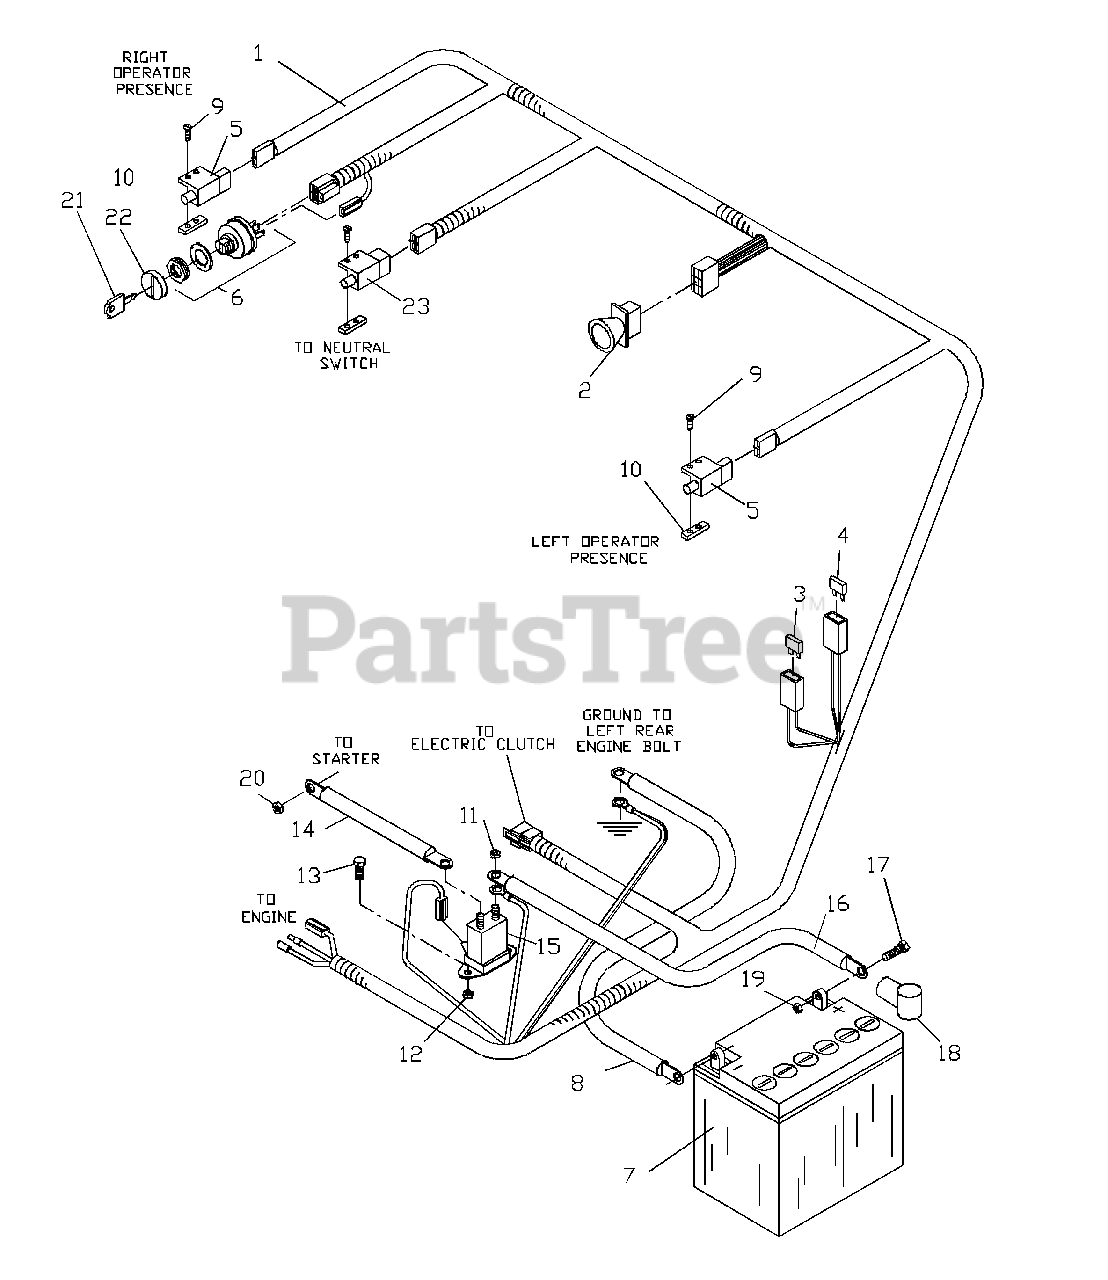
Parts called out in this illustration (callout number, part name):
1	WIRING HARNESS
2	CLUTCH SWITCH
3	FUSE 20 AMP
4	FUSE 7.5 AMP
5	SWITCH N. C.
6	IGNITION SWITCH
6	NUT, SWITCH
7	BATTERY
8	NEG. CABLE
9	SCREW #10-24
10	TAPPED PLATE
11	NUT 1/4
12	NUT 1/4 LOCK
13	HCS 1/4 X .625
14	POS. CABLE
16	POS. CABLE LONG
17	HCS 5/16 X .750
19	NUT 5/16 CTR. LOCK
20	NUT 1/4 NYLOC
23	2 POLE SWITCH
